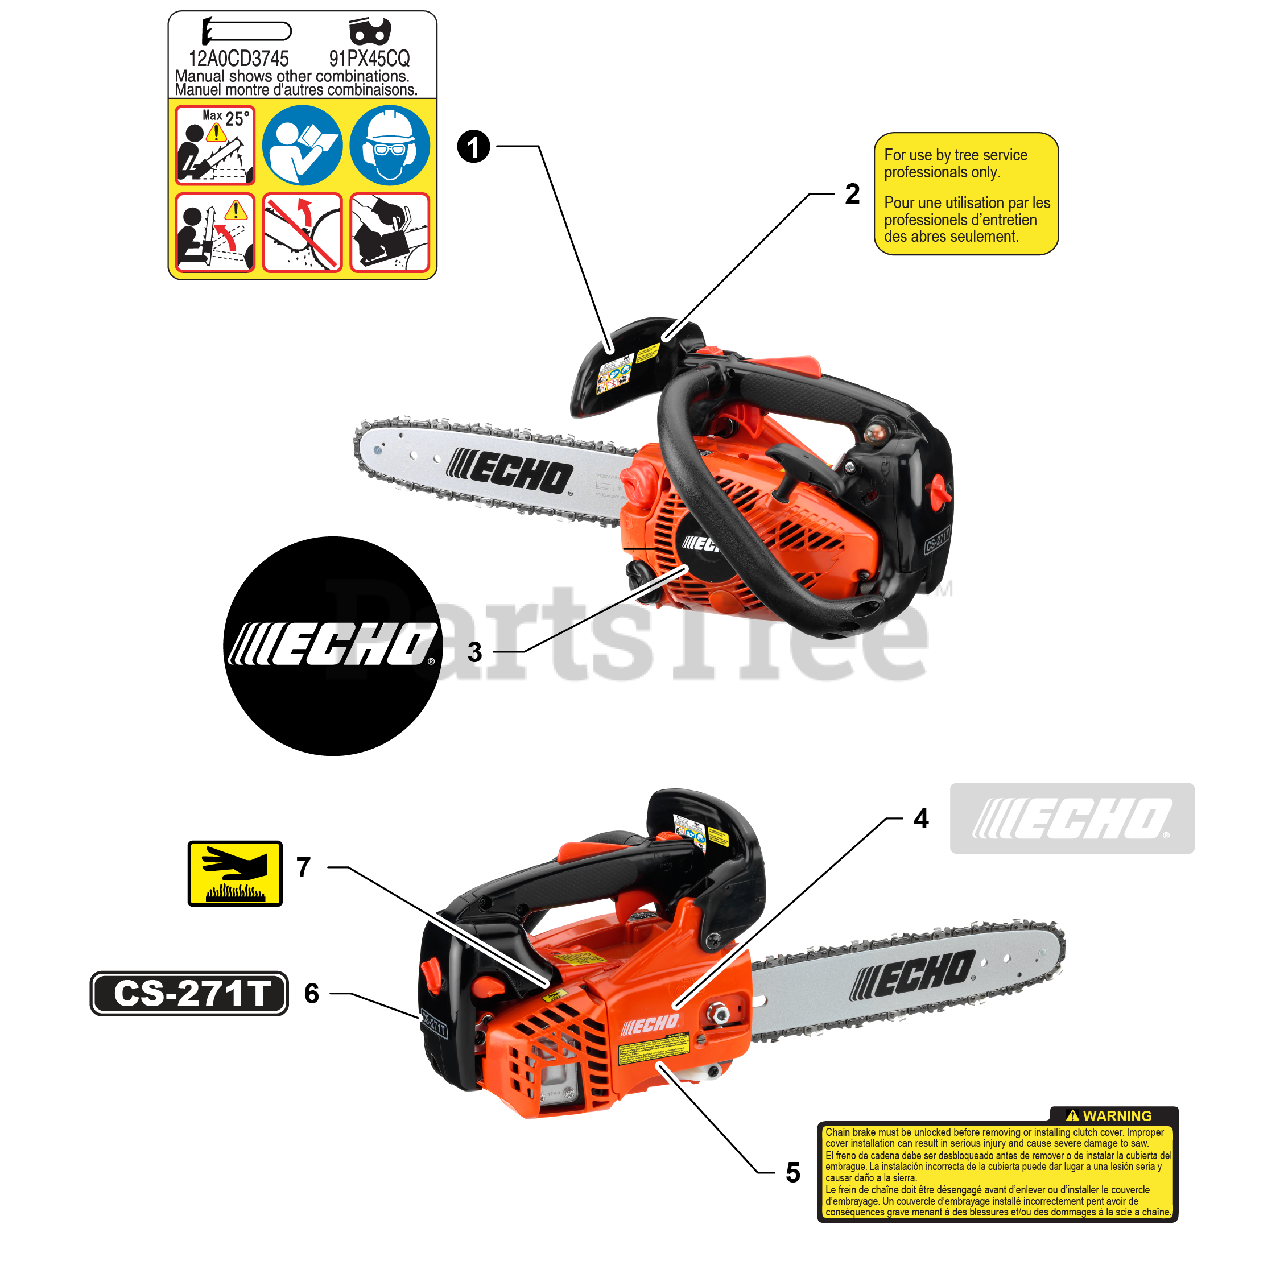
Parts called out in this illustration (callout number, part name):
1	LABEL, CAUTION
2	LABEL, CAUTION - PROFESSIONALS ONLY
3	LABEL, ECHO
4	LABEL, ECHO
5	LABEL, WARNING
6	LABEL - MODEL CS-271T
7	LABEL, CAUTION - HOT
